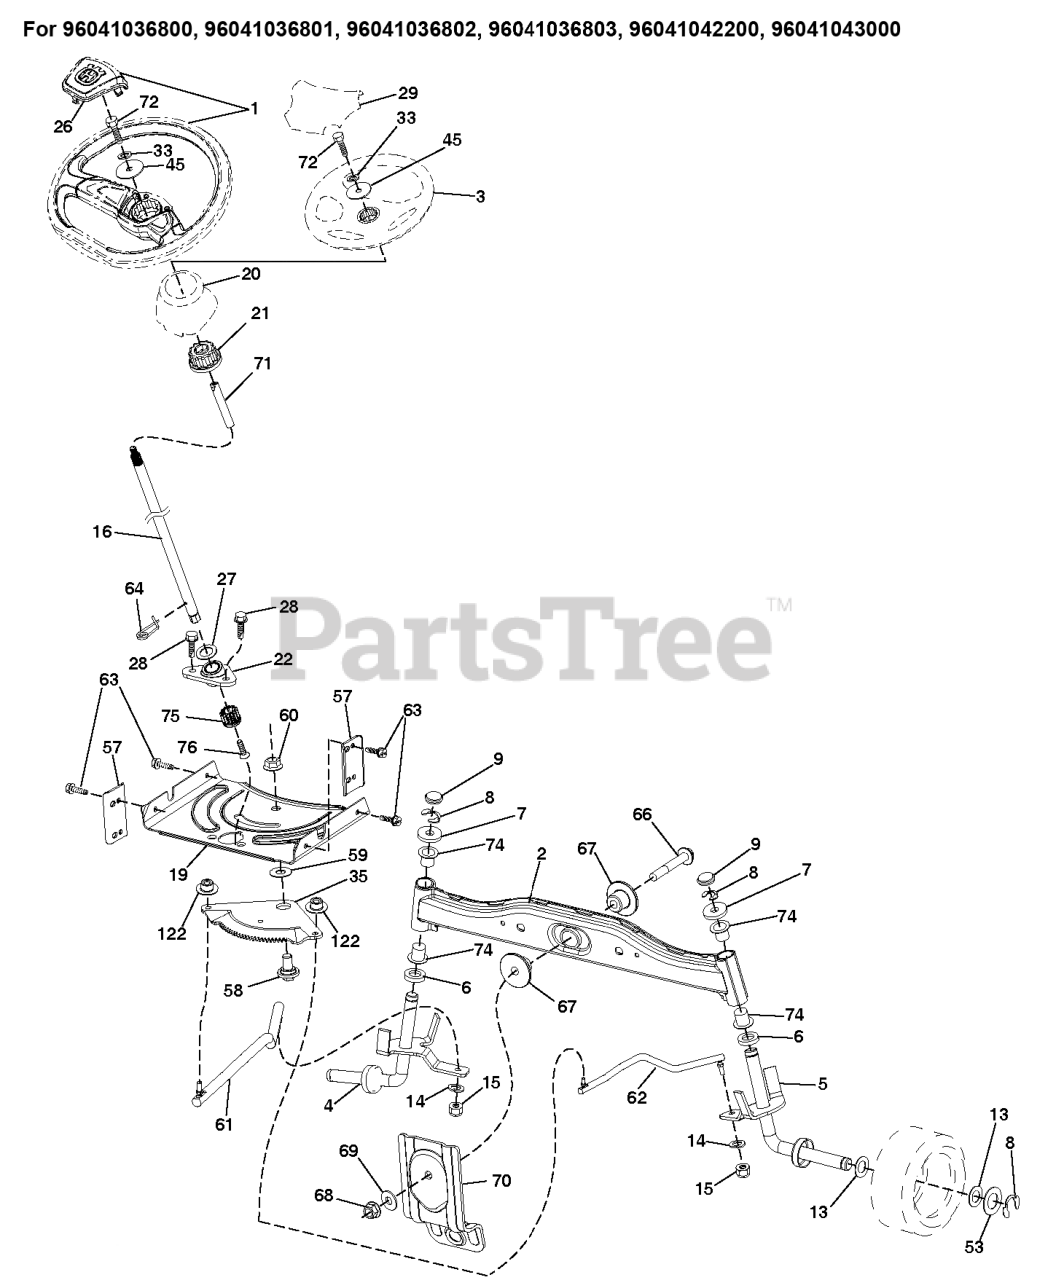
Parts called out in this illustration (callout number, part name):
1	Service Kit
2	AXLE HALF ASM-WELDED
3	WHEEL.STEERING.HUSQ.PREM.HRDRM
4	SPINDLE.WELDED.LH.15"TEX
5	SPINDLE.WELDED.RH.15"T
6	WASHER THRUST
9	CAP.SPINDLE.BLACK
15	NUT CROWNLOCK 3/8-24
16	3 HIGH.SHAFT-ZINC.PLATED
19	PLATE.STEER.DDL.NLT/NG
20	STEERING.BOOT.HUSQ.LT
21	ADAPTER, WHEEL STNG..
22	BEARING.SHAFT.STEER.LOWER.625
26	Steering
27	Washers
27	WASHER LT
28	SCREW, 3/8-16X3/4
29	INSERT.CAP.WHL.STRG.HUSQ.PREM
33	WASHER SPRING LOCK WASHER WITH
35	GEAR.SECTOR.PLATE.DDL.
53	WASHER.HARDENED
57	BRACKET.UPSTOP.TEX
58	BOLT.SHOULDER.SECTOR.P
59	WASHER.THURST.SECTOR.S
60	NUT FLANGE LOCK 5/8-11
61	DRAGLINK.LH.BALLSTUD.D
61	Links
62	Links
62	DRAGLINK.RH.BALLSTUD.D
63	SCREW
64	RETAINER.CLIP.SPRING.S
66	BOLT HEX FGHD 7/16-14 X 3 SERR
67	BUSHING.PM.FRONT AXLE
68	NUT.LOCK.FLANGE.7/16
69	WASHER.1.5X.505X.118
70	BRACKET.FRT.DECK.SUSP.RR.MT431
71	SHAFT.EXTEN.STRG.SPLINE
74	BEARING.STEERING.COLUMN
75	PINION.ZINC PLATED
76	SCREW HEAD SOCKET LRVB
122	CAP.GEAR.SECTOR.TEX
